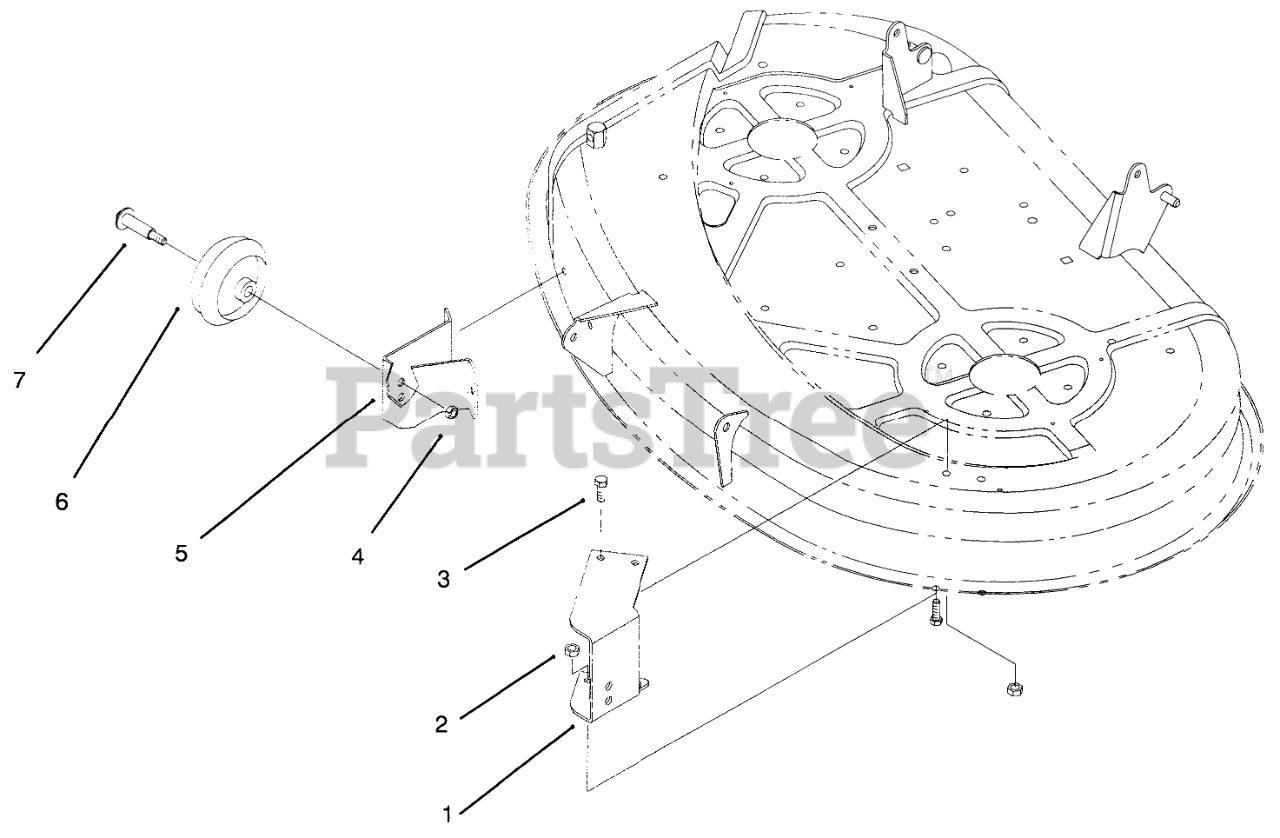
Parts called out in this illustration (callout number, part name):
1	Bracket-L.H.
2	NUT-LOCK, NI
3	SCREW-HH
4	NUT-LOCK, NI
5	Bracket-R.H.
6	WHEEL-GAGE
7	SCREW-SHOULDER, HWH
